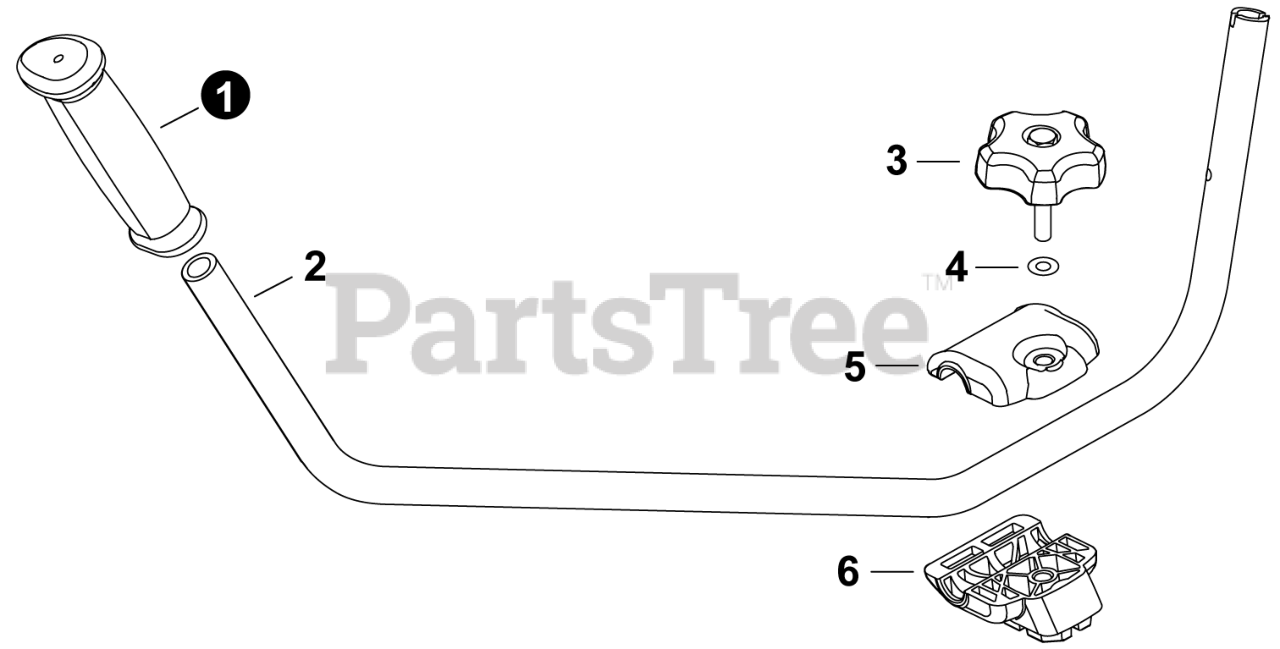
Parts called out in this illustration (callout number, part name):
1	GRIP, HANDLE
2	U-HANDLE
3	KNOB, SCREW M8
4	WASHER 8.2×17×1.6
5	BRACKET, HANDLE - UPPER
6	BRACKET, HANDLE - LOWER
